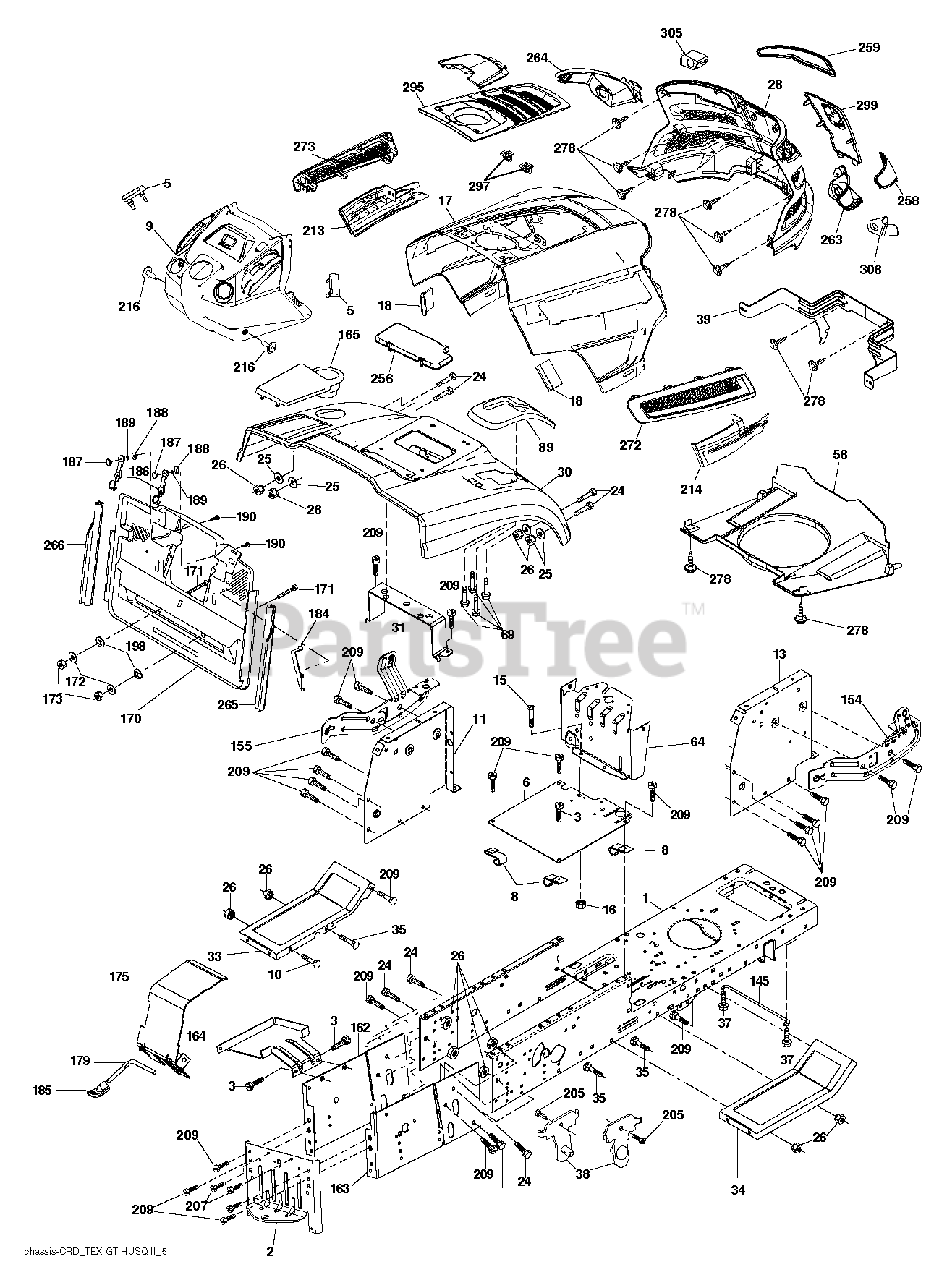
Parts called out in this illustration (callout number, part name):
2	DRAWBAR
3	SCREW 3/8-16X3/4
5	BUMPER DASH
6	PLATE
8	CLIP,INSULATOR
9	Husqvarna TBD
10	BOLT D
11	PANEL DASH LH
13	PANEL DASH RH
16	NUT
17	HOOD.ASM.HUSQVARNA.GT.TEX.ORAN
18	BUMPER.HOOD.TEX.HUSQVARNA
25	WASHER
26	NUT
28	GRILLE.SUBSTRATE.2011.
30	FENDER.PNT.CRD.MS-668
31	BRACKET SUPPORT FENDER
33	FOOTREST.PNT.LH.GREY
34	FOOTREST.PNT.RH.GREY
37	SCREW LT
38	BRACKET ASM PIVOT MOWER REAR
39	BRACKET.PIVOT.HOOD.GT.HUSQ.II
58	AIR.DUCT.GTV.BLACK
69	SCREW.HI-LO.CONSOLE
89	CONSOLE.CRD.AUTO.GRY
145	ROD.PIVOT.HOOD
162	BRACKET
163	BRACKET EXTEN CHASSIS RH CRD
165	COVER.BATTERY.BAG.ELE.CRD.498
172	WASHER
175	DOOR TRAP
179	ROD PIVOT FBI
184	BRACKET.ACTUATOR.BAGGER.SRD
185	KNOB.BRAKE.PARKING.ROD
186	LATCH ASSY
187	WELDNUT
189	LOCKWASHER (3 2)
190	SCREW
207	SCREW, 5/16-18 X 1/2
209	SCREW, 3/8-16X3/4
213	SIDE.TRIM.LH.GT.HUSQ.II.GRAY
214	SIDE.TRIM.RH.GT.HUSQ.II
216	SCREW 14-20 X 5/8
256	FENDER.PNT.CRD
258	LENS.HEADLIGHT.RH.GTII.2011
259	LENS.HEADLIGHT.LH.GTII.2011
263	BEZEL LIGHT.RH.GT.II.MYLAR
264	BEZEL LIGHT.LH.GT.II.MYLAR
265	SEALING
266	SEALING
272	VENT.SIDE.RH.GT.HUSQ.II.
273	VENT.SIDE.LH.GT.HUSQ.II.498
278	SCREW.#10 X 0.750.BOS
295	VENT.TOP.ASM.HUSQ.GT2
297	CLIP.RETAINER.TINNER.
299	APPLIQUE.SUBASM.GT.HUSQ.II
305	INSERT.REFLECTIVE.LH.HUSQ.GTII
306	INSERT.REFLECTIVE.RH.HUSQ.GTII
